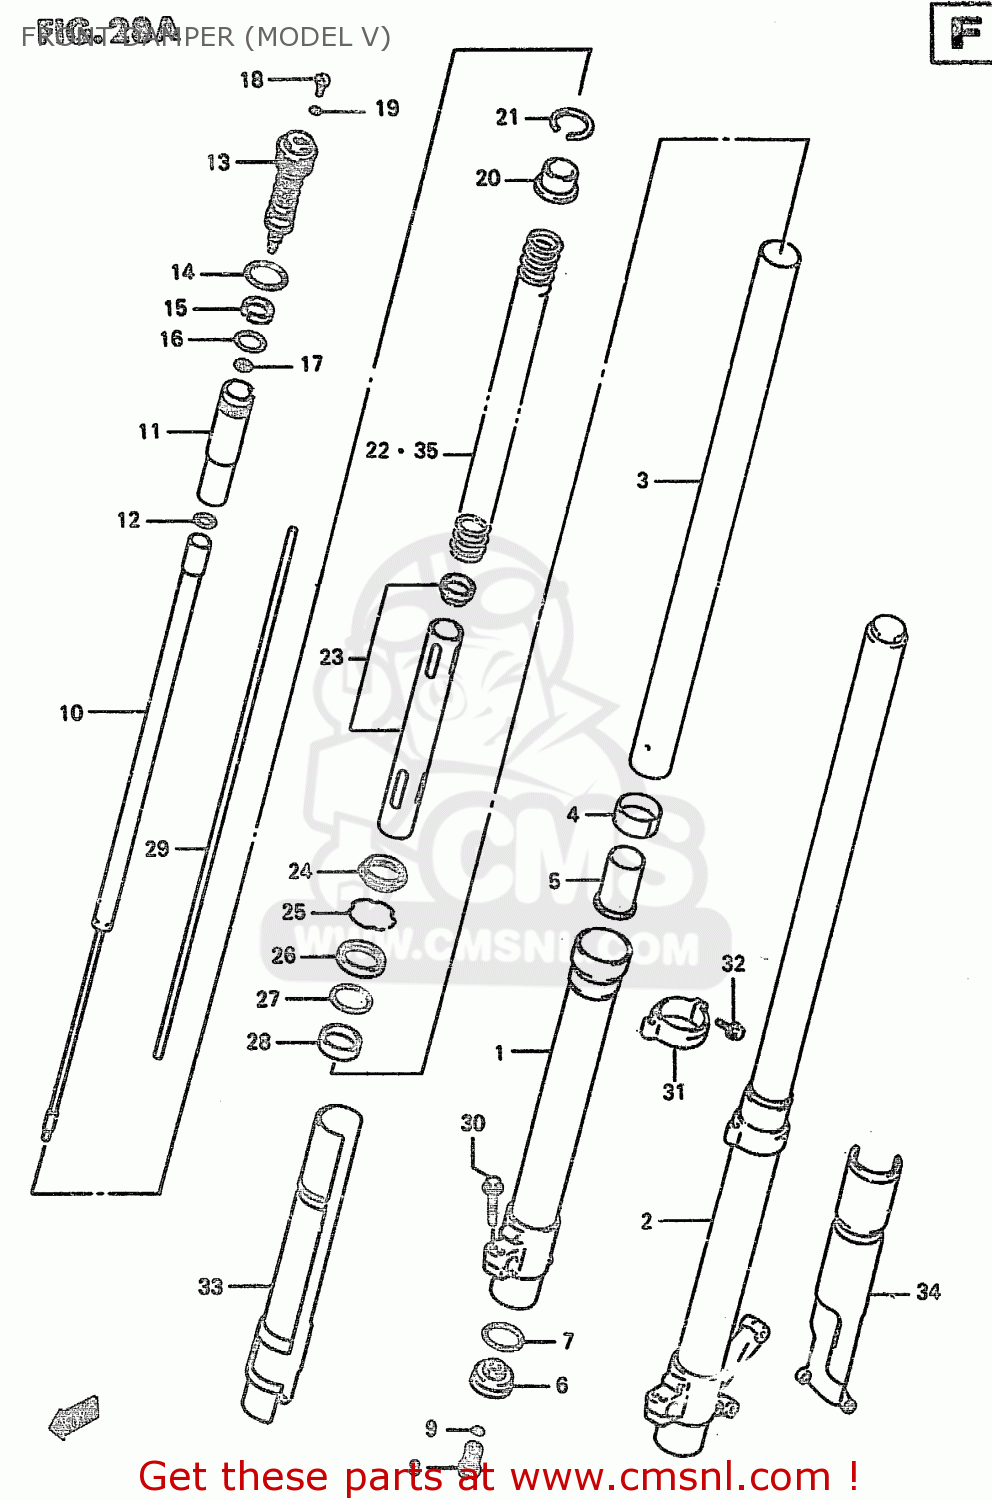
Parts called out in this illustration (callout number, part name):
1	TUBE,OUTER,RIGHT
2	TUBE,OUTER,LEFT
3	TUBE,INNER
4	BUSH,SLIDE
5	PIECE,OIL LOCK
6	PLATE,END
7	O RING
8	BOLT,CTR
9	O RING
10	ROD,FR DAMPER
11	TANK,SUB
12	O-RING
13	BOLT,FORK
14	O RING
15	BUSH,FORK BOLT SLIDE
16	O RING
17	O RING
18	BOLT,PLUG
19	O RING,PLUG
20	SPRING,STOPPER
21	RING,STOPPER
22	SPRING,FRONT (K=0.42)
23	COLLAR,SPRING
24	SEAL,DUST
25	RING,STOPPER
26	SEAL,OIL
27	SPACER,SEAL
28	BUSH,GUIDE
29	ROD,PUSH
30	BOLT,HANDLE HOLDER(8X35)
31	GUIDE,FR PROTECTOR,R
32	BOLT,PROTECTOR GUIDE,6
33	PROTECTOR,OUTER TUBE,R
34	PROTECTOR,OUTER TUBE,L
35	SPRING,FR(K=0.40)
